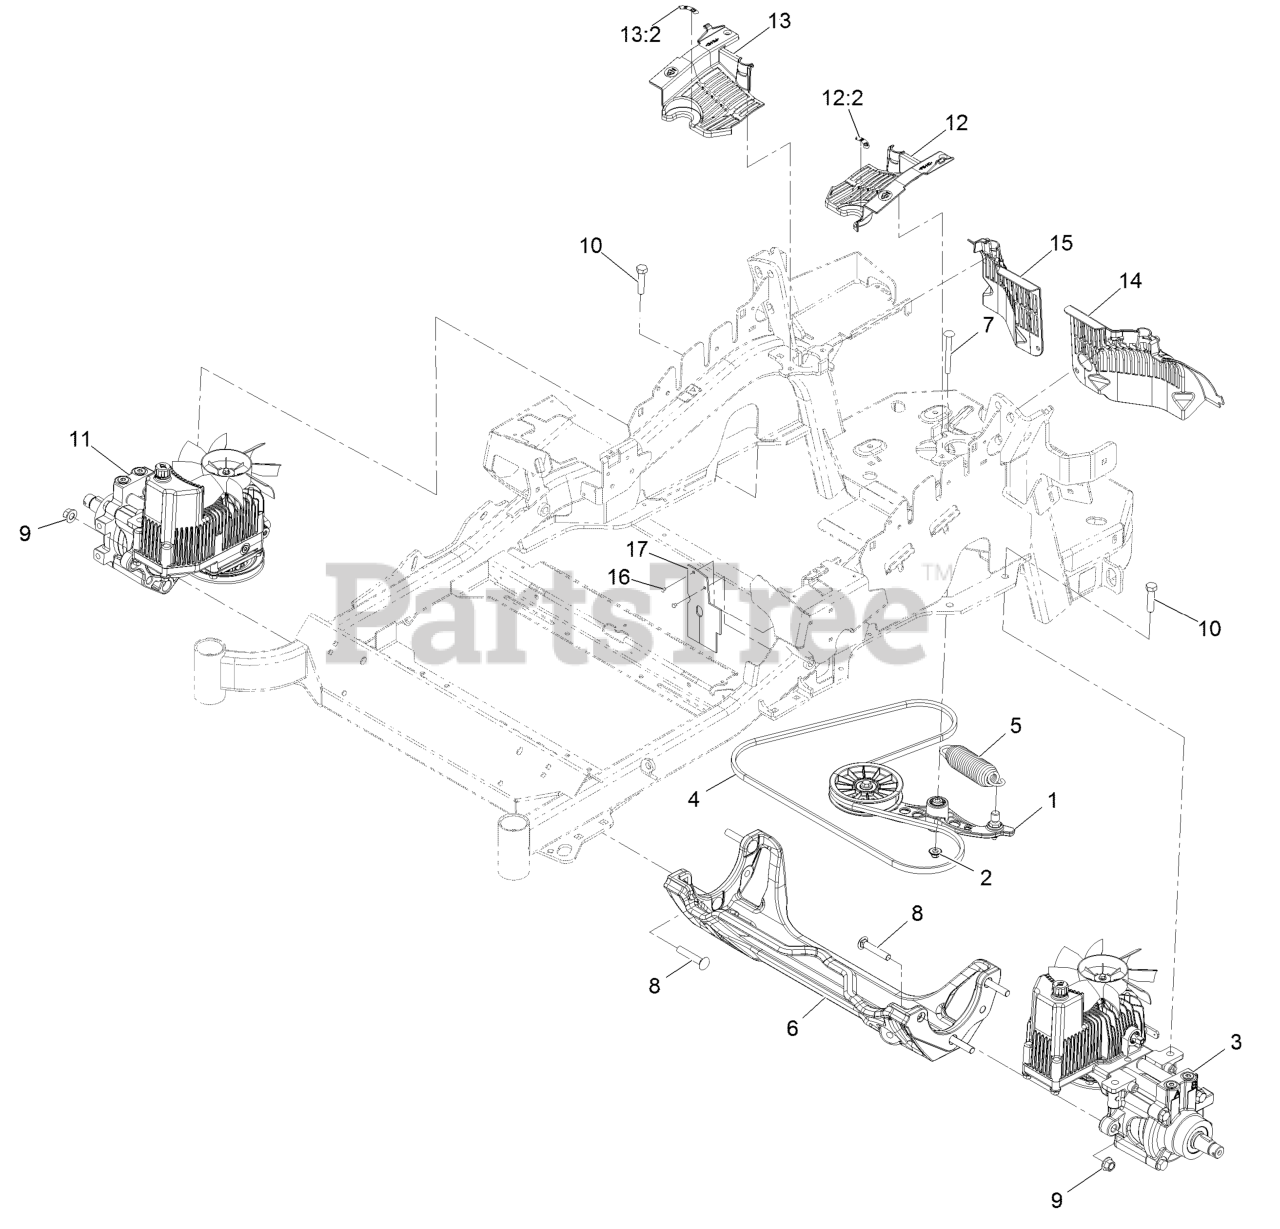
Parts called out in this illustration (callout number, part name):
2	FAN KIT
3	PULLEY KIT
4	HANDLE-BYPASS VALVE, HYDRO
5	DIPSTICK-HYDRO W/GASKET
6	GASKET-DIPSTICK, HYDRO
7	SWASH BLOCK KIT
8	PUMP SEAL KIT
9	MOTOR SEAL KIT
10	TUBE SEAL KIT
11	OUTPUT SHAFT SEAL KIT
12	NOSE CUP-UHT
13	KEY-WOODRUFF
15	HOUSING-HYDRO, LH
16	MOTOR-HYDRAULIC LH 240CC
17	MAGNETIC PLUGS SERVICE KIT
18	CHECK VALVE ASM
19	PLUG-CHECK (W/O-RING)
21	O-RING-CHECK VALVE
22	SCREW HH
23	SCREW-HSH
24	HYDRAULIC TUBE KIT
